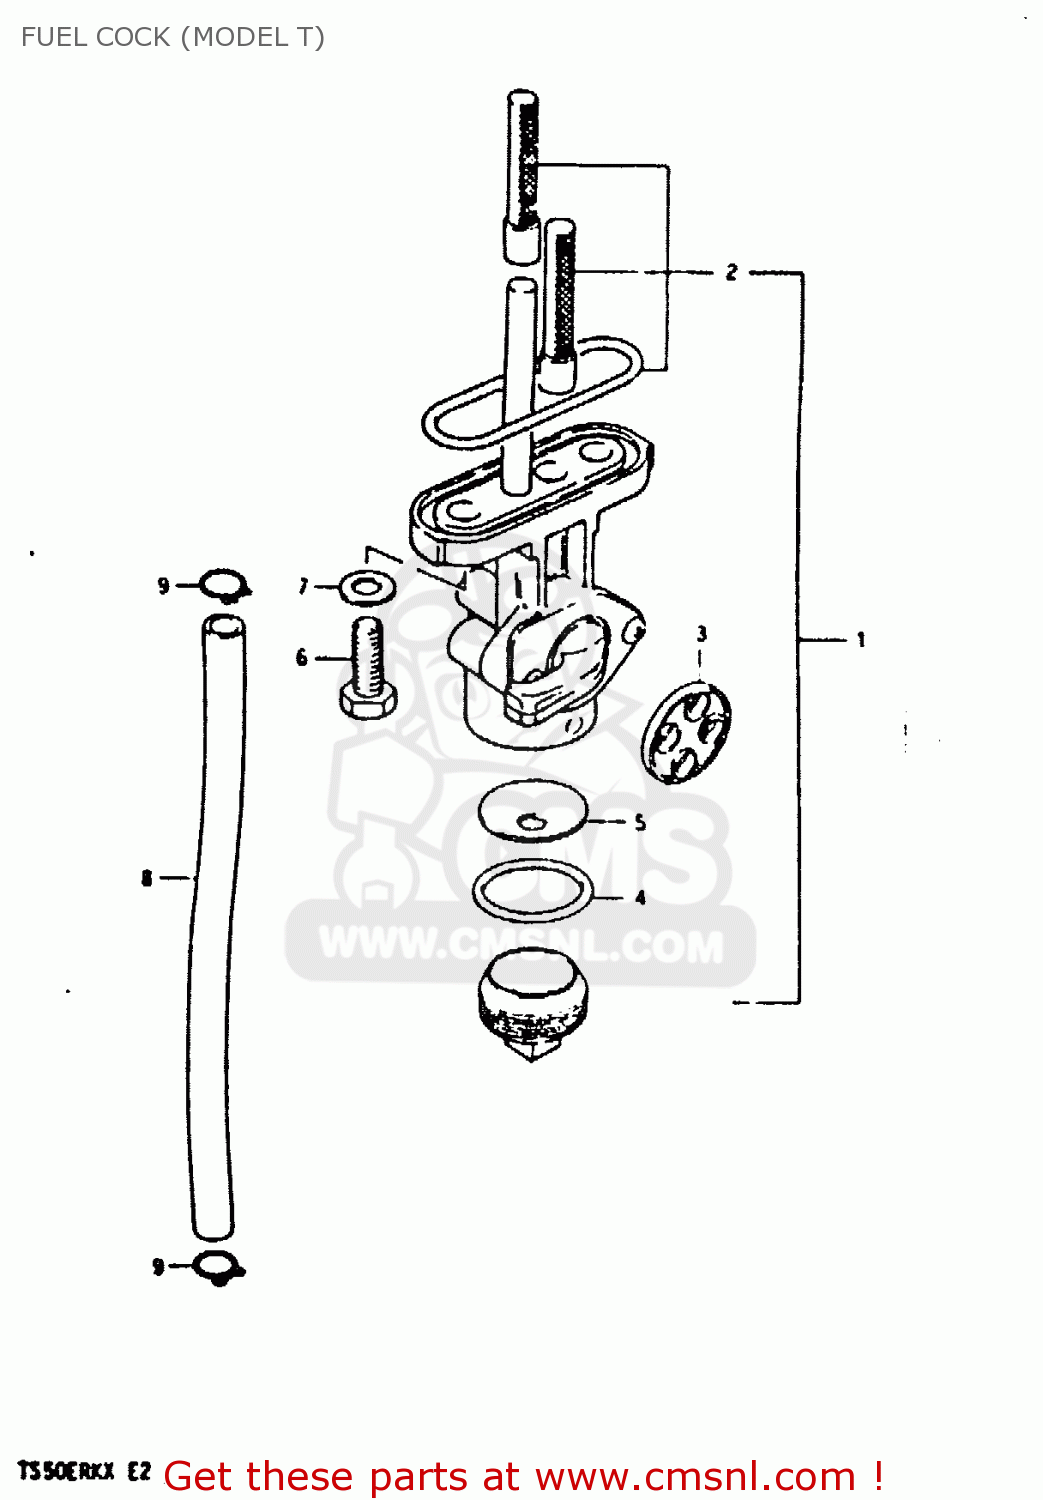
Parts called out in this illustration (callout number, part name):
1	COCK ASSEMBLY,FUEL
2	FILTER SET,FUEL COCK
3	GASKET,LEVER (NAS)
4	GASKET,FILTER (NAS)
5	NET,STRAINER
6	BOLT(6X20)
7	GASKET
8	HOSE
9	CLIP
